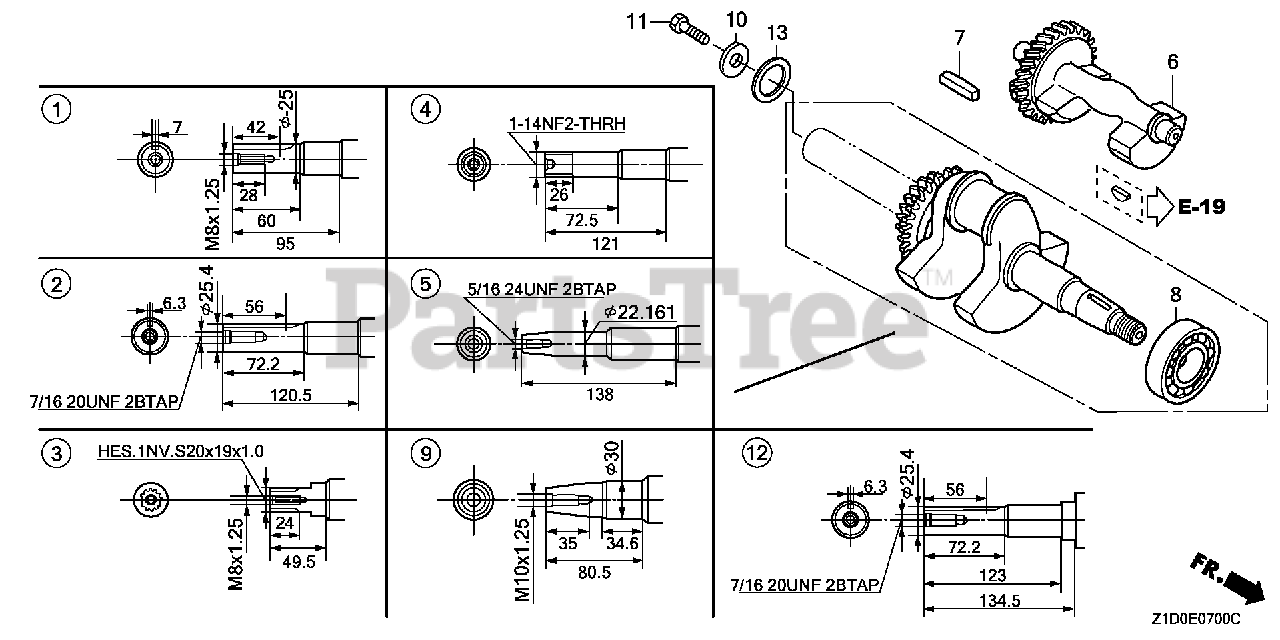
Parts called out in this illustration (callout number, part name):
7	KEY (6.3X6.3X43)
8	BEARING, RADIAL BALL (6206 SH)
12	CRANKSHAFT (Q-TYPE)
13	WASHER, THRUST (30MM)
